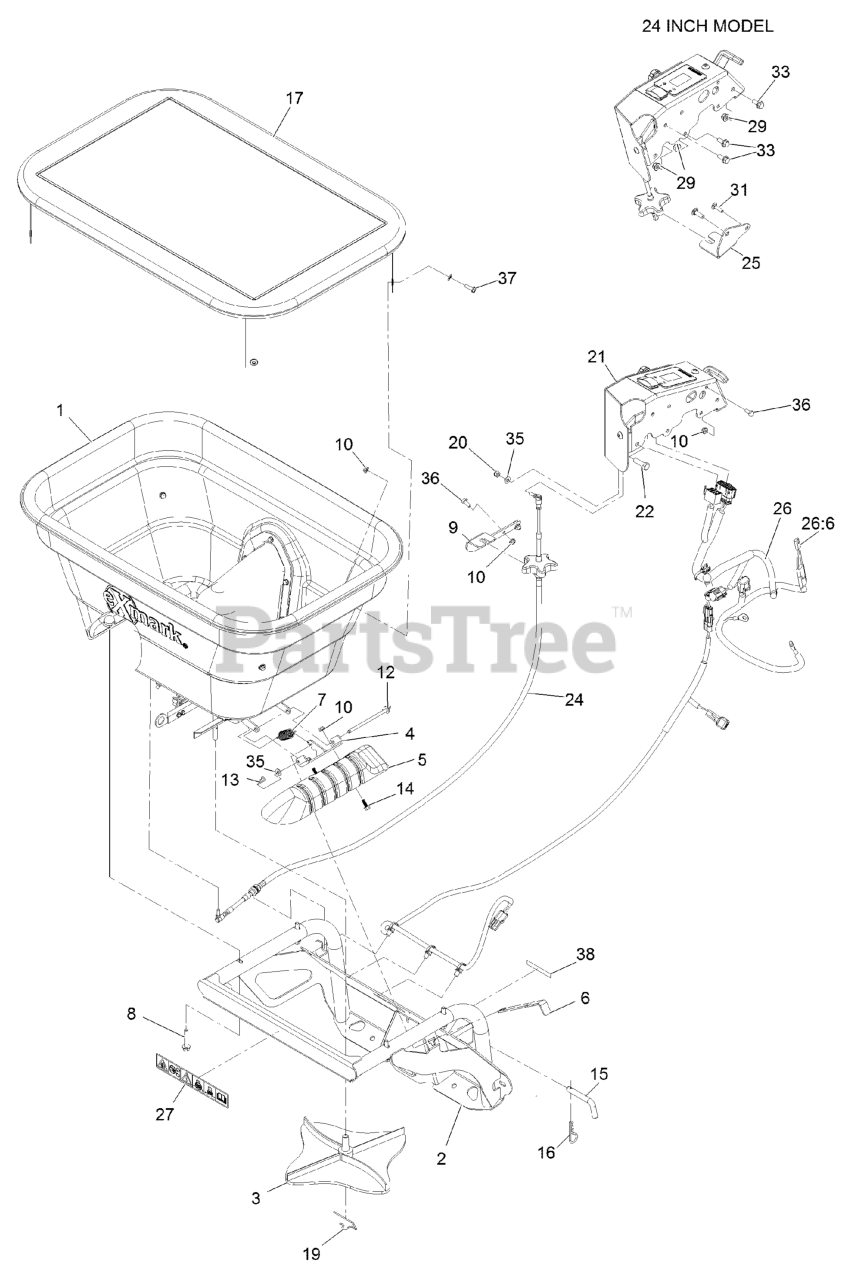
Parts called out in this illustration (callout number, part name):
1	Asy-Spreader Hopper (Exmark)
2	SPREADER HOPPER FRAME ASM
3	SPINNER-SPREADER
4	BRACKET-DEFLECTOR
5	DEFLECTOR
6	STRAP-ENGAGEMENT
7	Spring-Extension
8	Screw-HWH
9	BRACKET-CABLE
12	PIN-PIVOT
13	PIN-COTTER
14	SCREW-HHF
15	PIN-HITCH
16	PIN-HAIR
17	COVER-HOPPER
19	CLIP-SPINNER
20	NUT-LOCK
21	Spreader Controller ASM
22	SCREW-HH
24	CABLE-PUSH, PULL
25	BRACKET-CABLE
26	HARNESS
26:6	CONNECTOR
27	DECAL-DOWN, TIE
29	NUT-HF, NI
31	SCREW-CARR
33	SCREW-HHF
35	WASHER-FLAT
36	SCREW-HH
37	SCREW-HWH
38	DECAL-WARNING
